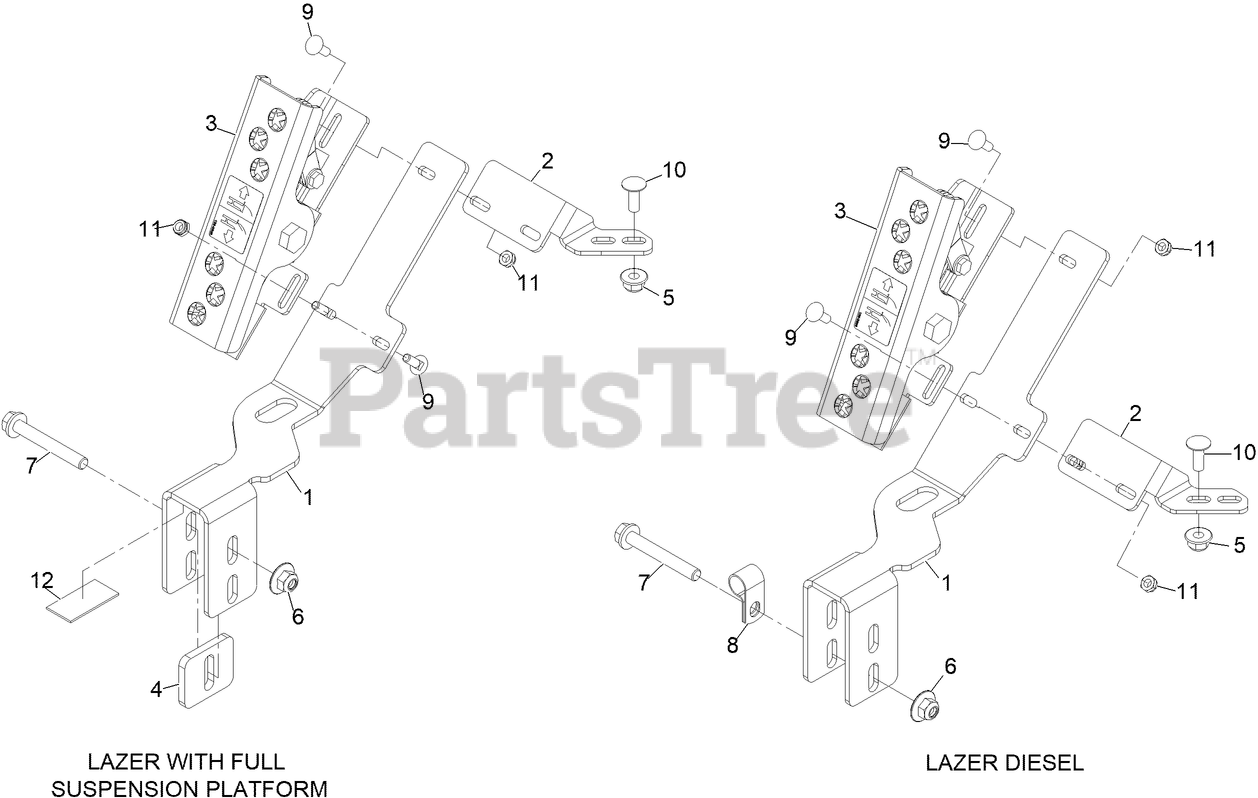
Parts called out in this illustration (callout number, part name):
1	BRACKET- PEDAL
2	Bracket, Support [red]
3	ASM- Pedal
4	SPACER- PEDAL MOUNT
5	NUT-HF, NI
6	Nut-Nyloc 3/8-16 Flg
7	SCREW-HFH
8	Clamp-R
9	BOLT-CARR
10	BOLT-CARR
11	NUT-LOCK, NI
12	PAD-RUBBER
